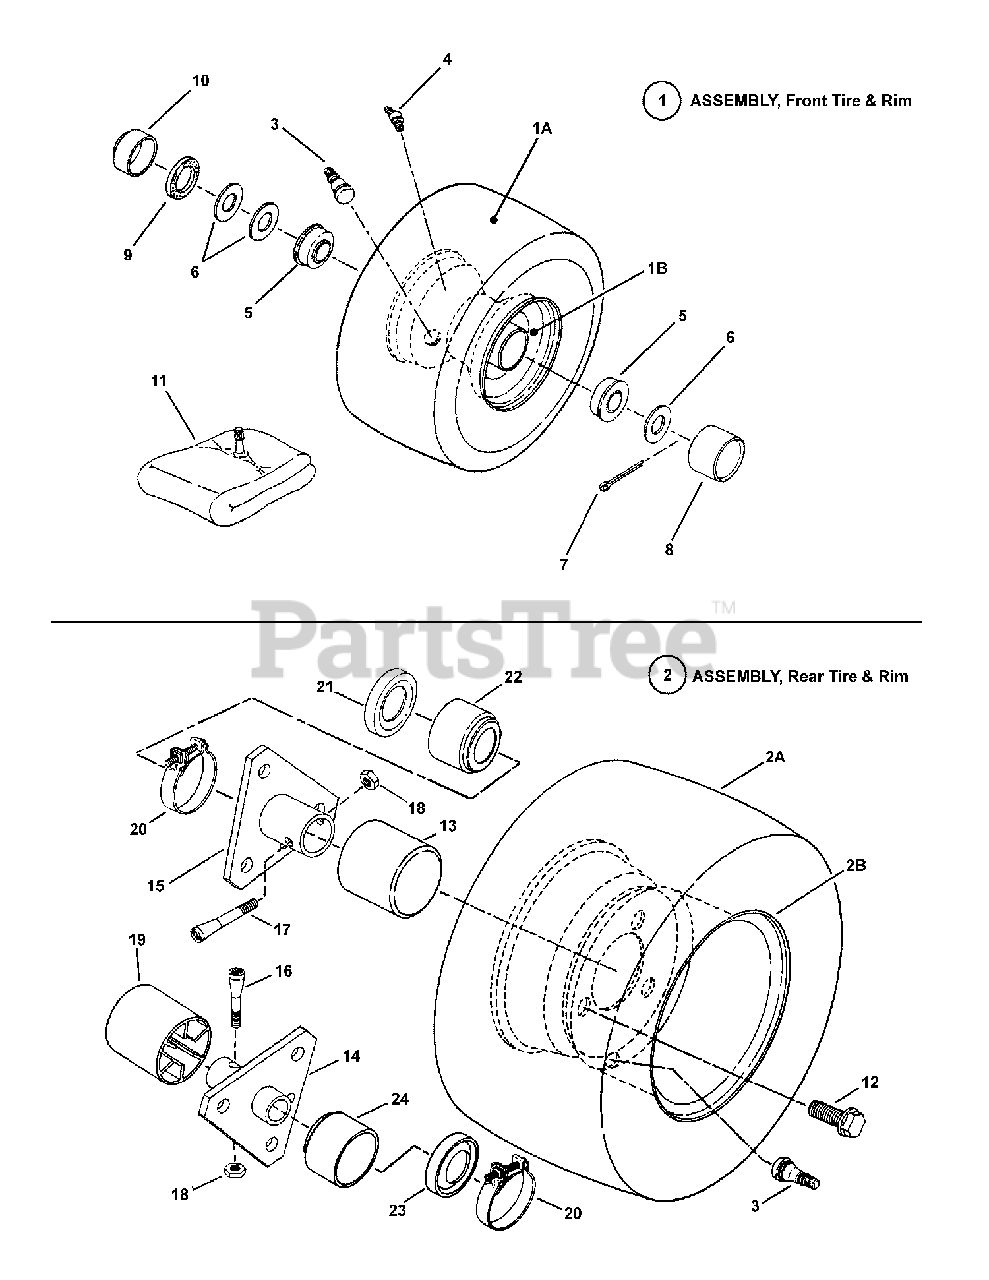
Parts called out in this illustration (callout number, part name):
1	ASSEMBLY, Front Tire & Rim (Complete)
1A	TIRE, 11 x 4.00-4 (Kenda)
1B	RIM, (For 4.10/3.50 x 4 Tire)
2	ASSEMBLY, Rear Tire & Rim
2A	TIRE, 16-6.50 x 8 (28" & 33" Models)
2B	RIM, Extra Wide (For 16/7.50 x 8 Tire)
3	VALVE STEM, Snap In
4	* LUBE Fitting, Straight (for 3/16" hole)
4	* LUBE Fitting, Straight (for 1/4" hole)
4	* LUBE Fitting, 90 Degree, Ball Check (for 1/4" hole)
4	* LUBE Fitting, 90 Degree, Ball Check (for 5/16" hole)
5	BALL BEARING, Flange (3/4" I.D.)
6	WASHER, .77 x 1.13 x .06 Flat
7	COTTER PIN, 5/32 x 1"
8	HUB CAP
9	FELT SEAL
10	CAP, Dust
11	TUBE, Inner (For 4.10/3.50 x 4 Tire)
12	BOLT, 1/2-20 x 3/4" Lug, GR 5
13	HUB CAP, R.H. (1.35" ID x 2.25") (Short Axle)
14	HUB, Wheel LH, 3 Hole 3/4" ID
15	HUB, Wheel RH, 3 Hole 1" ID
16	BOLT, 5/16-24 x 1-5/8" Tapered (Left Hand)
17	BOLT, 5/16-24 x 2" Tapered (Right Hand)
18	NUT, Hex Lock 5/16F GR.C YZ
19	HUB CAP, L. H. (.975" ID x 2.25") (Long Axle)
20	CLAMP, Boot, 2"
21	SEAL, 1.22" ID x 1.875" OD
22	CAP, Seal 1.0" ID x 1.67" OD
23	SEAL, OIL .750" ID x 1.832" OD
24	CAP, Seal 3/4" ID x 1.875" OD
